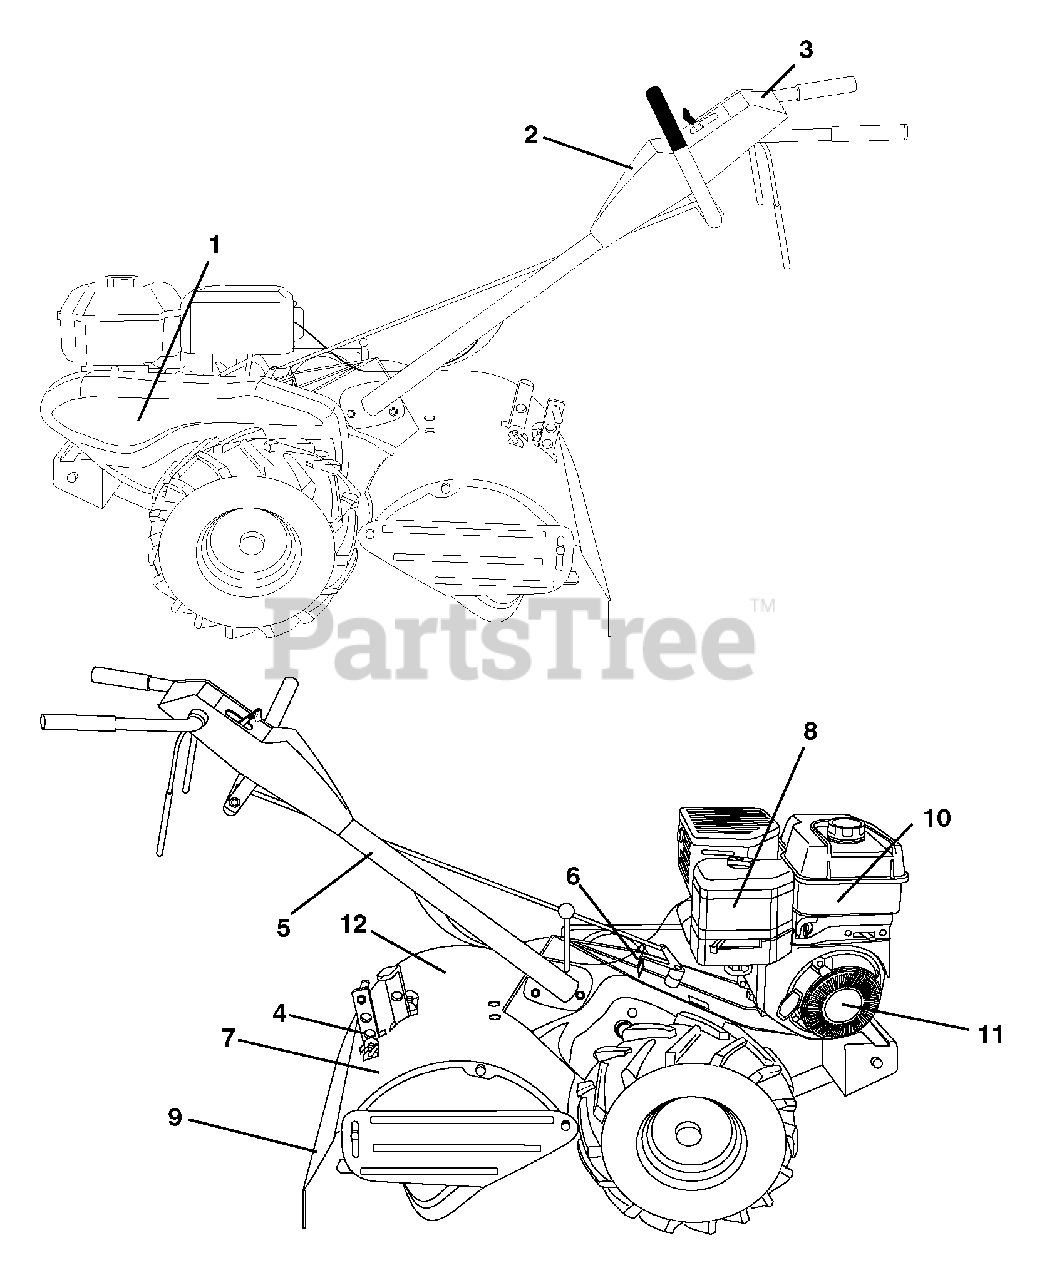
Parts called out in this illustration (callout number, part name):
1	Decal, Belt Guard
2	Decal, Console
3	Decal, Console
4	Decal, Tine Shield
5	Decal, Hand Placement
6	Decal, Shift Indicator
7	Decal, Reverse
8	Decal, Engine B&S
9	Decal, Warning, Rotating Tines
10	Decal, Engine Intek REF
11	Decal, Rewind Intek #274350
12	Decal, Forward
